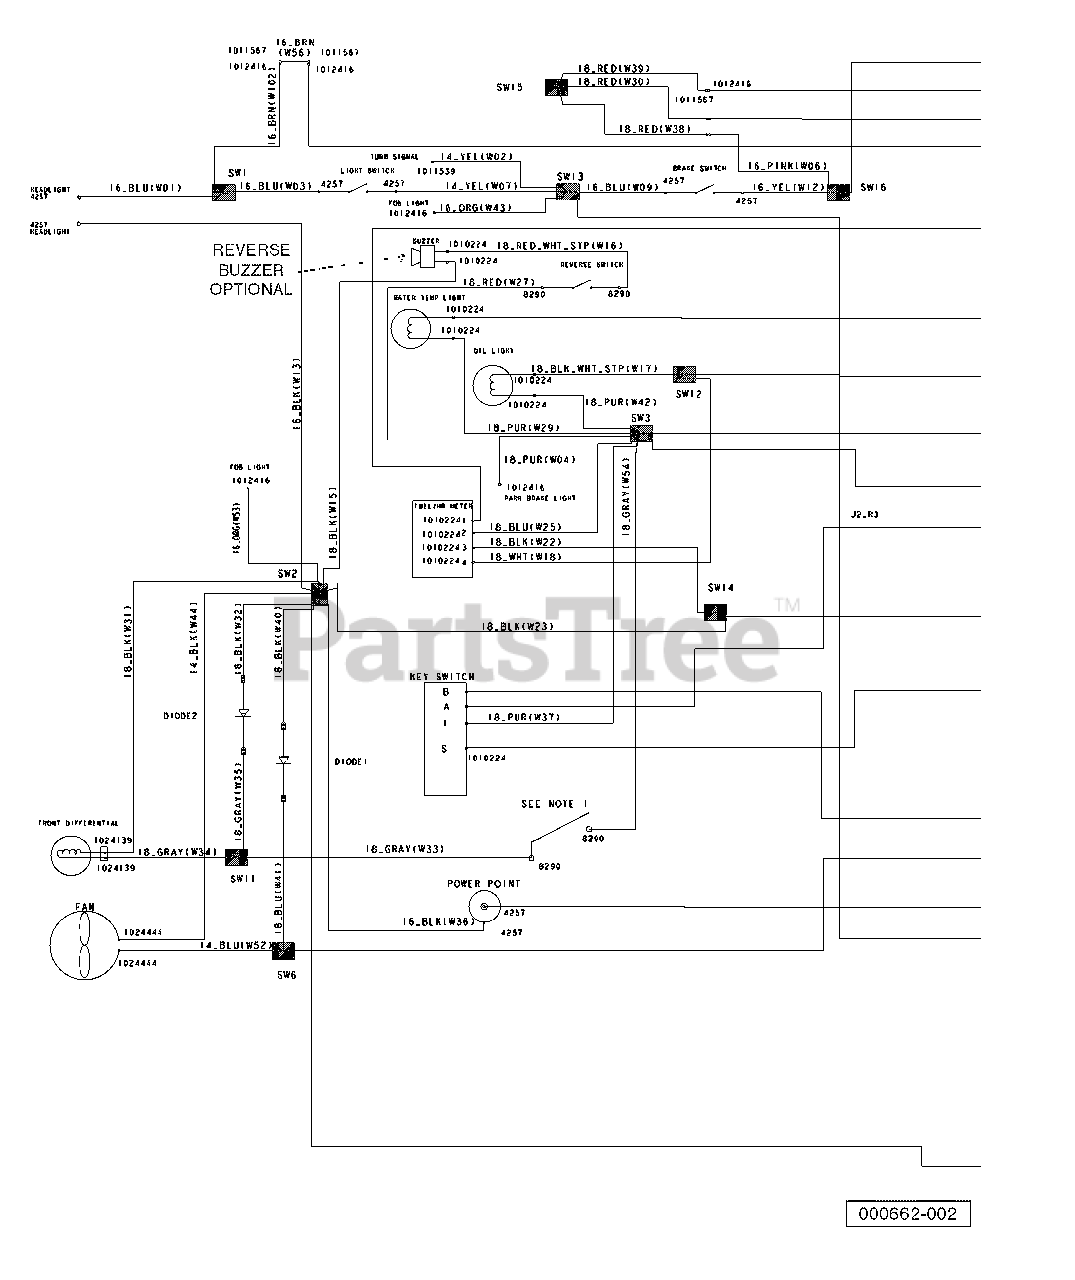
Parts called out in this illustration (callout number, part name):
1	Diode, General Purpose, 6.0a
2	Harness, Diesel AWD
3	Asm, Switch, Limit, Awd
